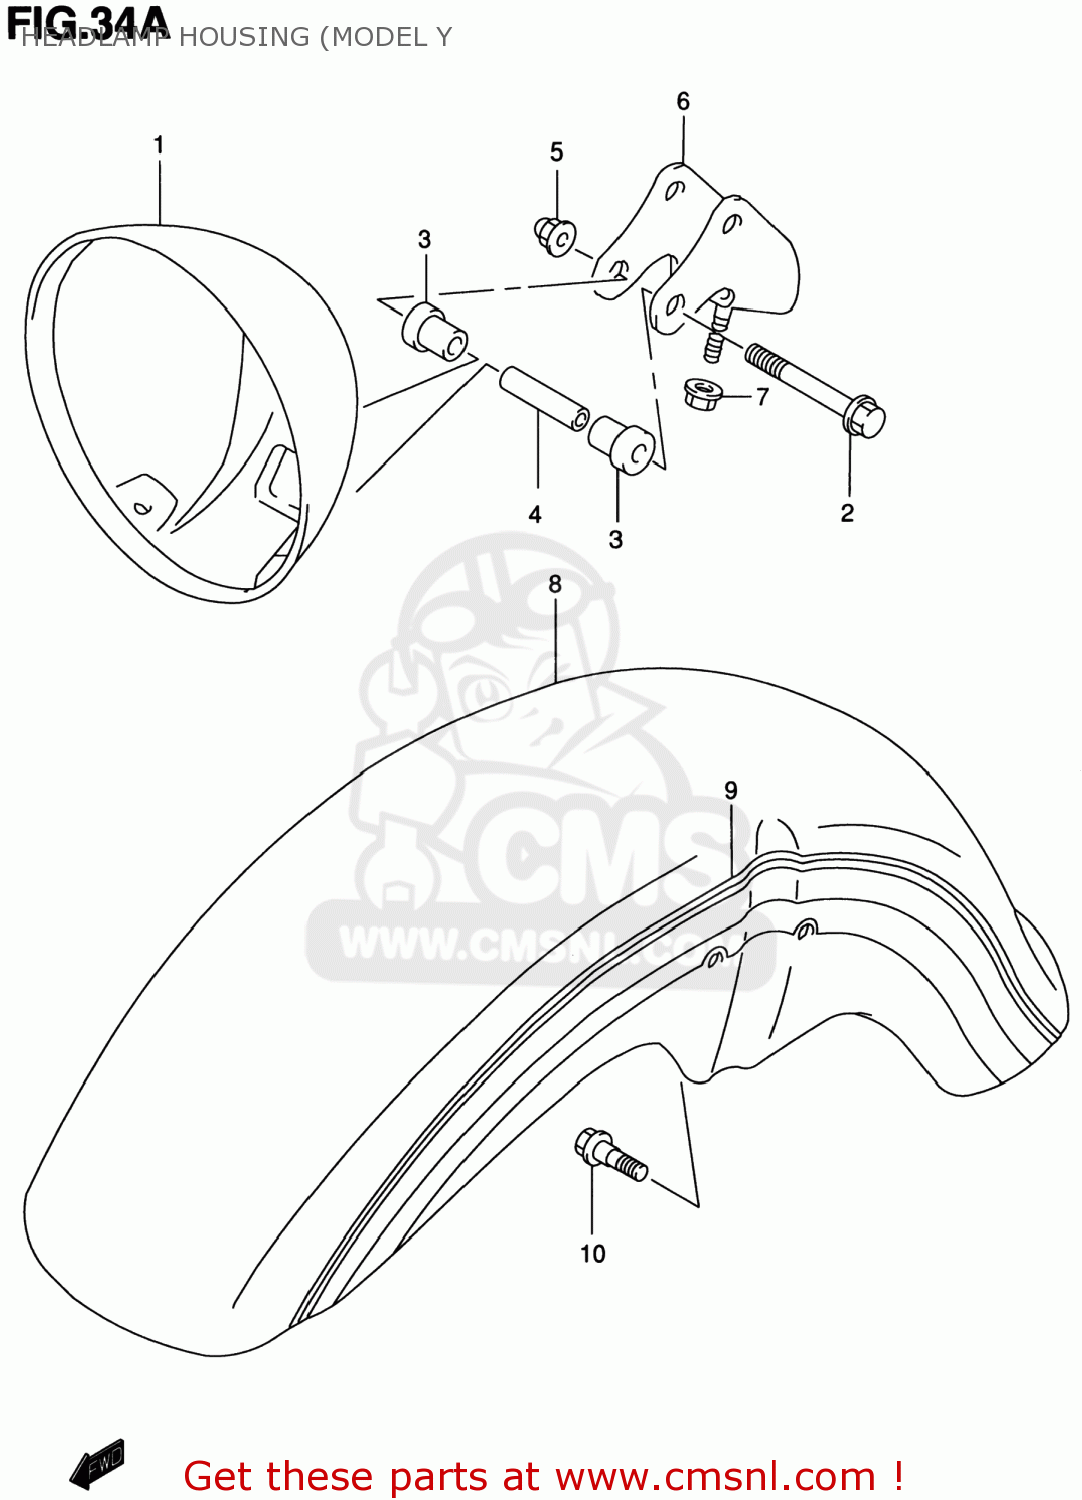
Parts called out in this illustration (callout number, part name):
1	HOUSING,HEADLAMP
2	BOLT
3	CUSHION,HEADLAMP HOUSING
4	SPACER(6.5X9X38.3)
5	NUT
6	BRACKET,HEADLAMP HOUSING
7	NUT
8	FENDER,FR
9	TAPE SET,FR FENDER
10	BOLT(6X16)
